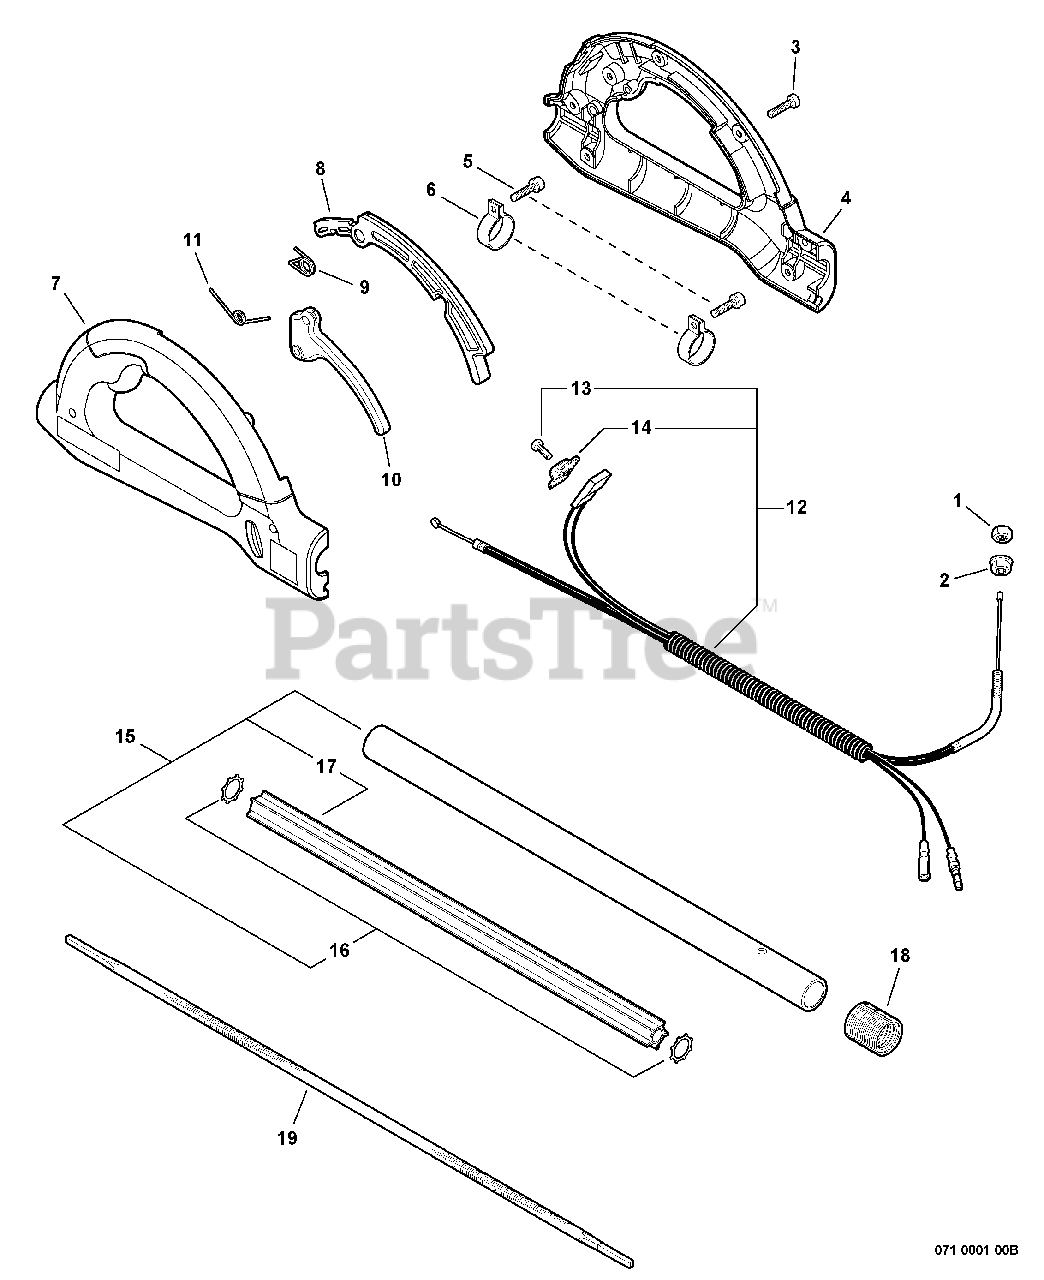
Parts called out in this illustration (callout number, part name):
2	NUT, FLANGE M6
3	SCREW M5×18
4	HANDLE, RIGHT
5	SCREW M5×20
7	BODY, HANDLE - LEFT
8	LOCKOUT, THROTTLE
9	SPRING, TORSION
10	TRIGGER, THROTTLE
11	SPRING, TORSION
12	CONTROL CABLE ASSY
13	SCREW 3×10
14	KNOB, SWITCH - ORANGE
15	MAIN PIPE ASSY
18	TUBE, FLEXIBLE
19	DRIVESHAFT - FLEXIBLE
